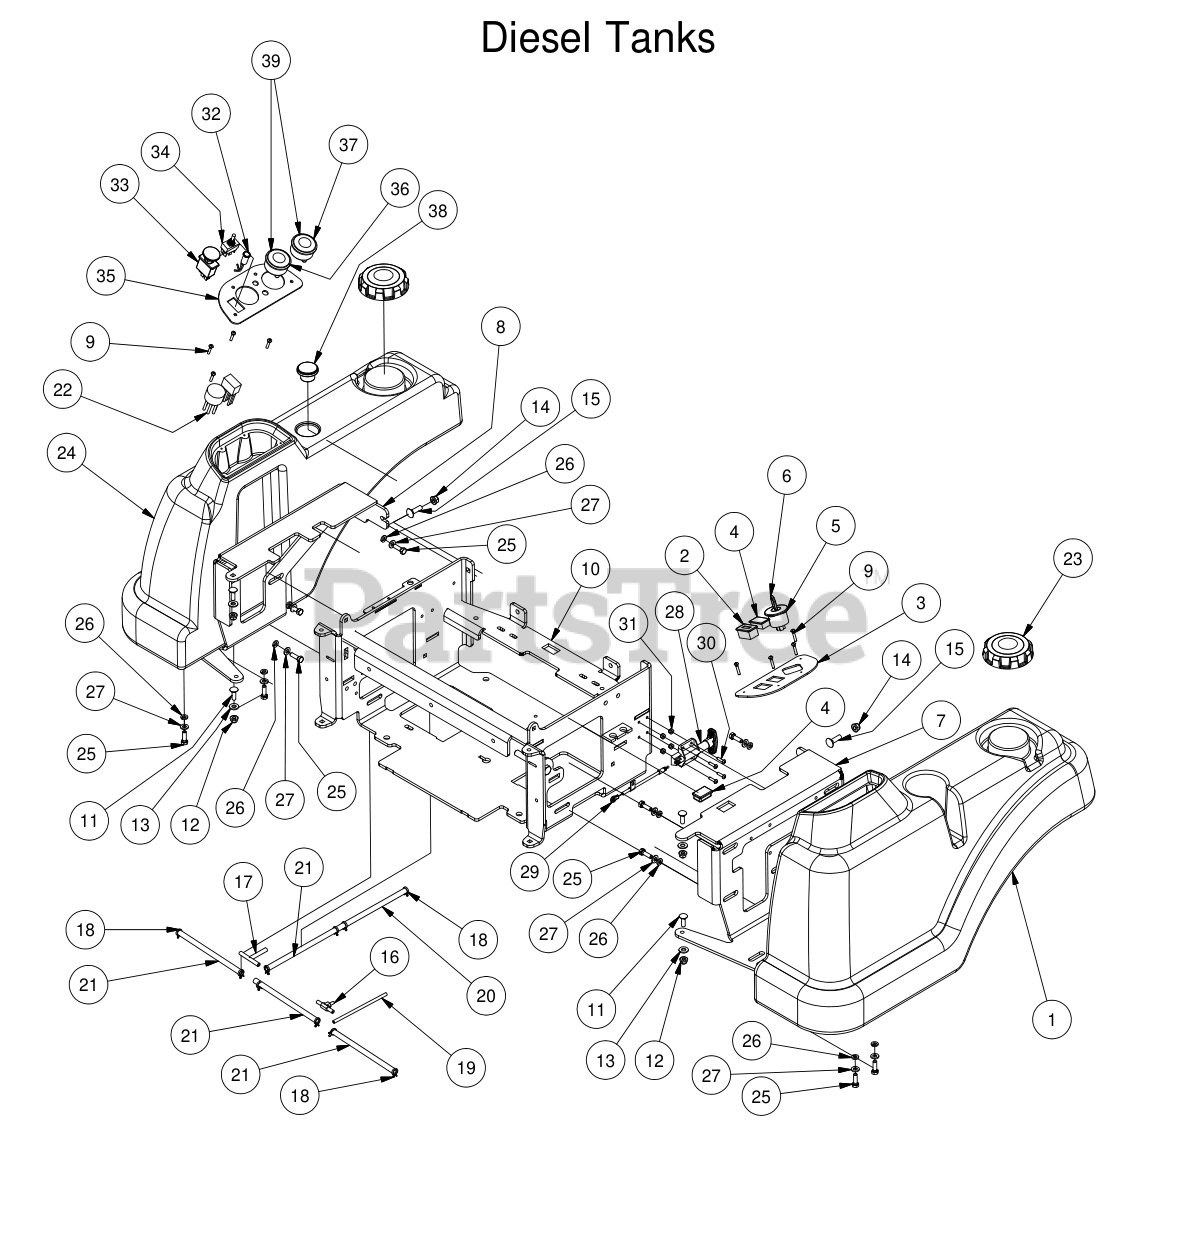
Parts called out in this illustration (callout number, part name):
1	Left Fuel Tank with Fender
2	Hour Meter
3	Control Panel (Left)
4	Light Plug
5	Ignition Switch
6	Ignition Key
7	Left Tank Support
8	Right Tank Support
9	10-32 x 1 Button Head Bolt
10	Diesel Seat Frame
11	5/16" x 1" Carriage Bolt
12	5/16" Flange Nut
13	.360 ID Plastic Washer
14	3/8" Nylock Flange Nut
15	3/8" x 1 1/4" Carriage Bolt
16	Brass fuel line T
17	fuel line T
18	1/4 Fuel Hose Clamp
19	3/16 Fuel Line
20	5/16" fuel line hose
21	1/4" Fuel Line Hose
22	Wiring Harness -35 & 28 Diesel
23	Diesel Fuel Cap - 3.5" Neck
24	Right Fuel Tank with Fender
25	5/16" x 1" Bolt
26	5/16" Lock Washer
27	5/16" Flat Washer
28	2016 T Handle Release
29	2015 Seat Latch Cable
30	10-24 x 1 BS C/S 18-8 SS
31	10-24 Nylon Insert Locknut Zinc Orange Nylon
33	PTO Engager
34	Deck Lift Joystick
35	Diesel Control Panel Right 2012
36	2" Water Temperature Gauge
37	2" Oil Pressure Gauge
38	Fuel Gauge and Grommet
39	Pigtail-2" Faria Gauge -2012 & up (Used For the water and Oil Gauges)
